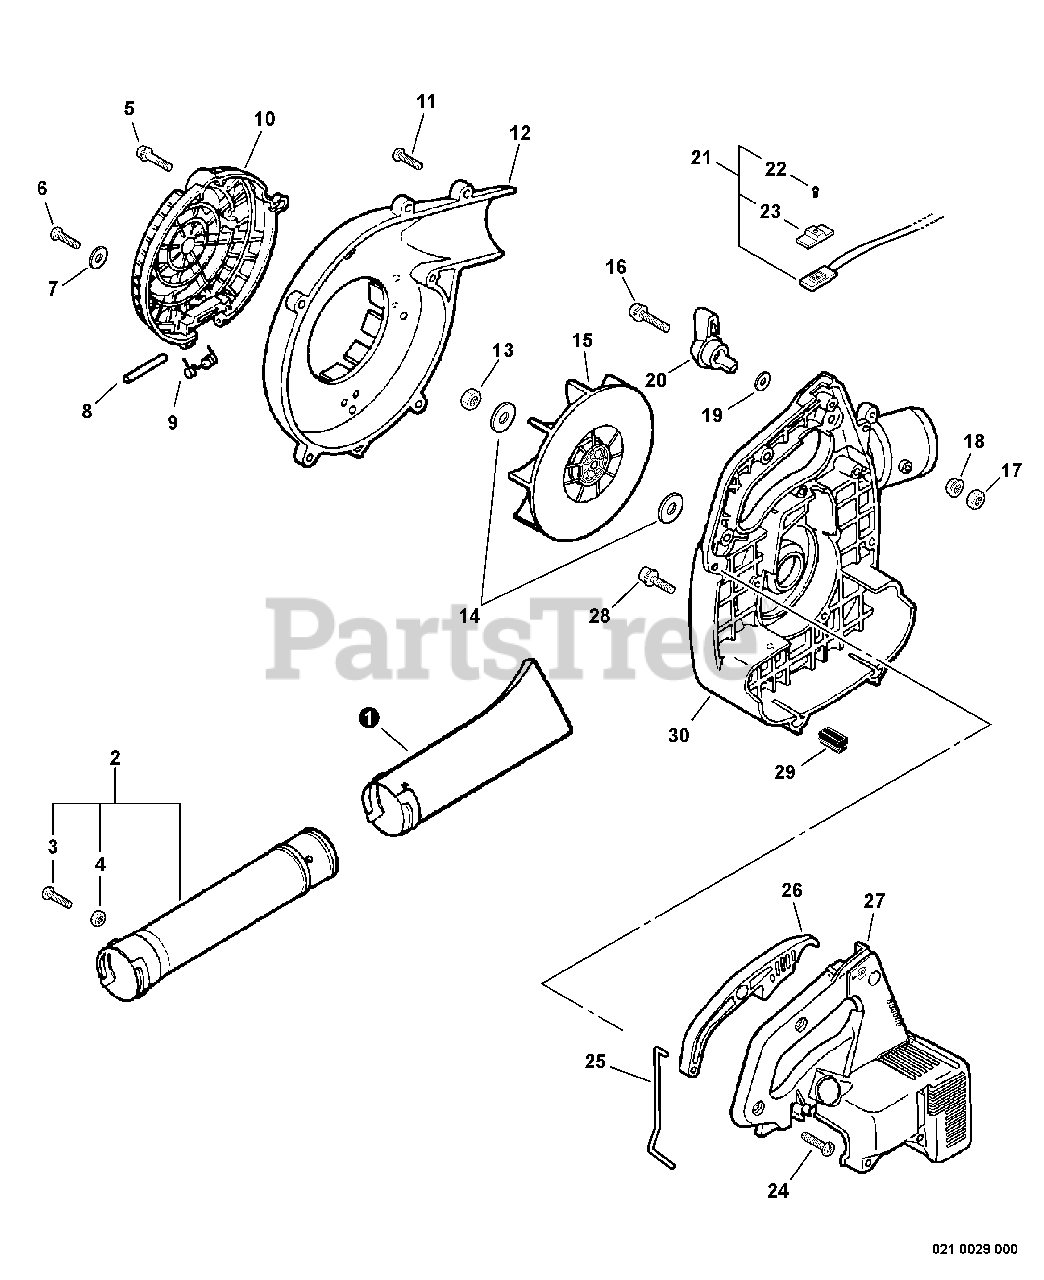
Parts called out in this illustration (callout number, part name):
1	TUBE, BLOWER - NOZZLE
2	TUBE, BLOWER - STRAIGHT
3	SCREW - 5X10
6	SCREW - 5X14
7	WASHER - 5
10	GUARD, DEBRIS
11	SCREW - 5X20 -- TAPPING
12	COVER, FAN - LEFT
14	WASHER - 8
16	SCREW - 5X25
18	NUT - 5 -- FLANGE
19	WASHER - 5
20	LEVER, THROTTLE - BLACK
21	IGNITION SWITCH ASSY
22	SCREW - 3X10
23	KNOB, SWITCH - ORANGE
24	SCREW - 5X20 -- TAPPING
25	ROD, THROTTLE
26	TRIGGER, THROTTLE - BLACK
27	COVER, ENGINE
28	SCREW - 4X22
30	COVER, FAN - RIGHT
